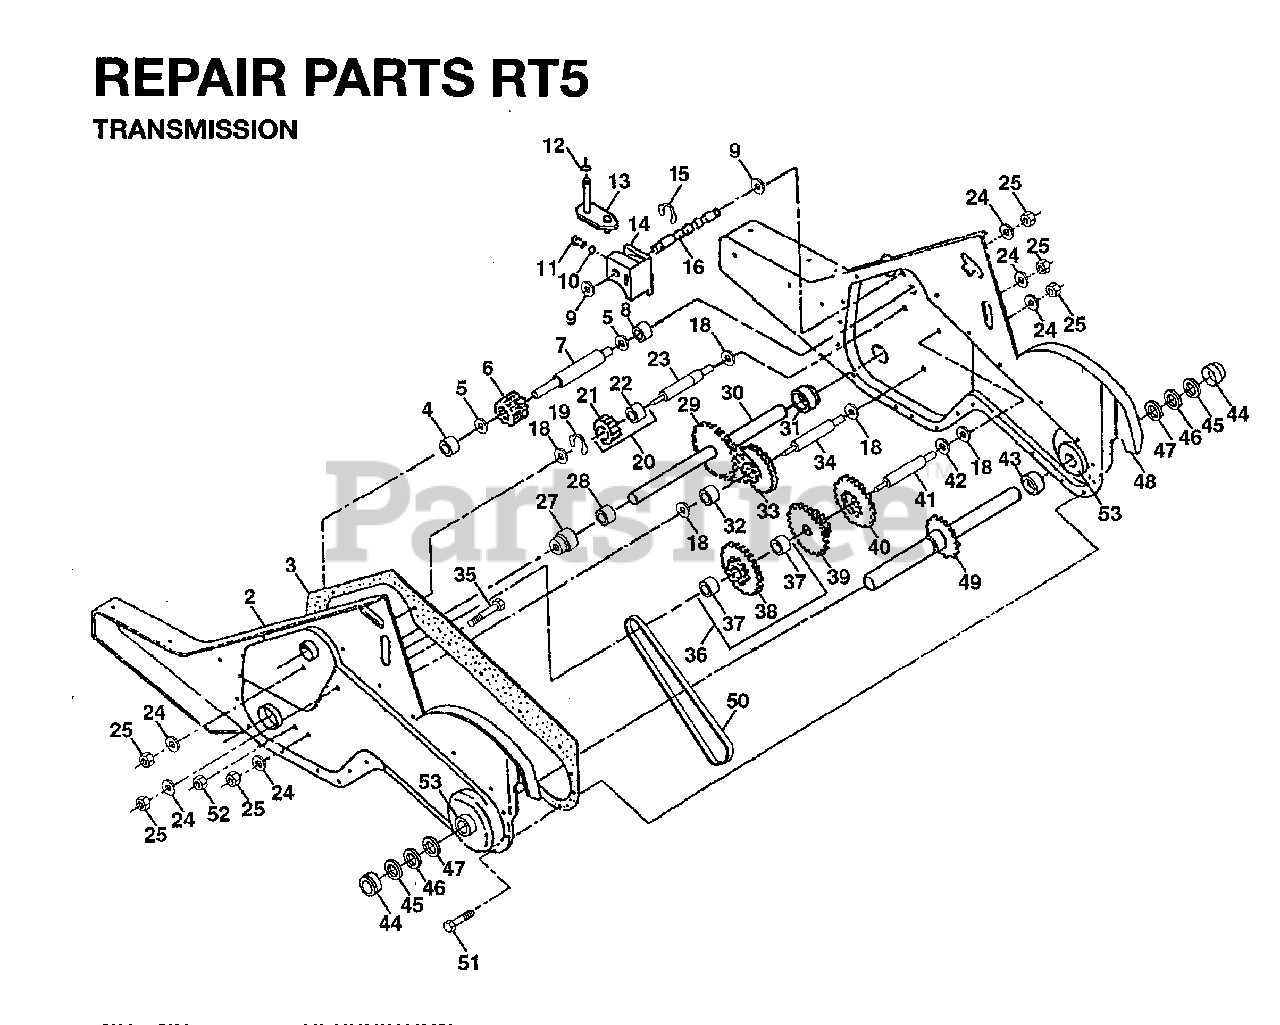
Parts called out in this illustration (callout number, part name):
1	HEX BOLT
3	WASHER
5	LOCKNUT
9	LOCKWASHER
11	BOLT HEX**
12	TRANSMISSION.ASM.W/1".D-SHAFT
13	WASHER - M12
15	LOCKNUT
18	LOCKWASHER
